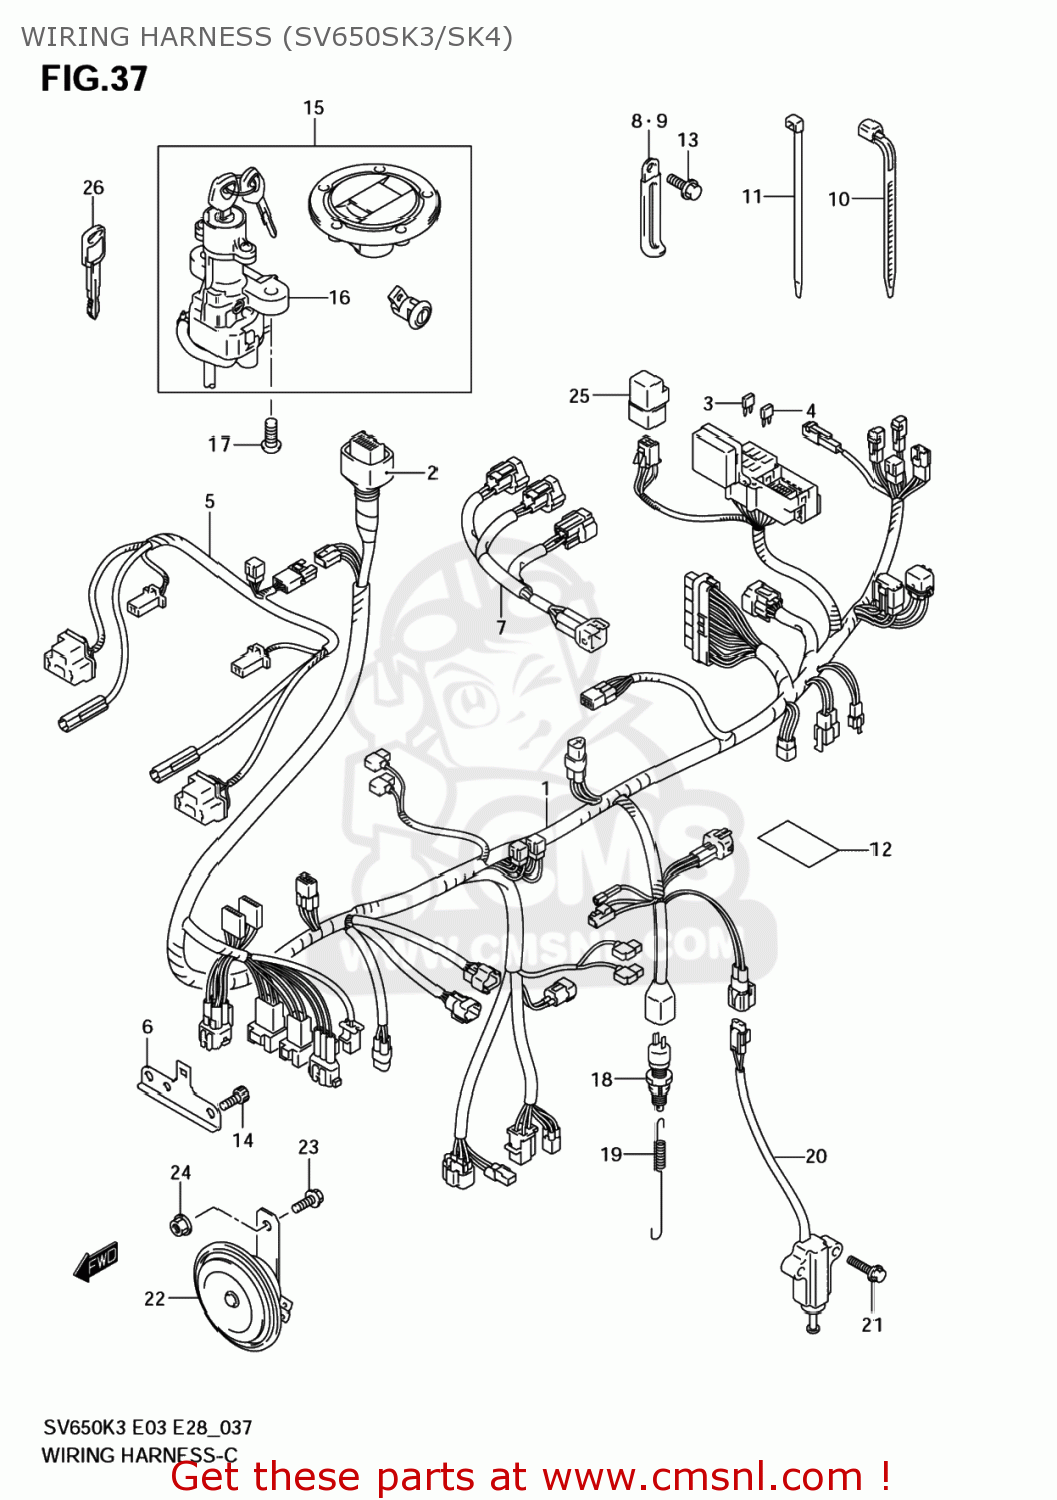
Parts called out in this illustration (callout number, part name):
1	HARNESS,WIRING NO.1
2	COVER,SPEEDOMETER COUPLER
3	FUSE(10A)
4	FUSE(15A)
5	HARNESS,WIRING NO.2
6	HOLDER,COUPLER
7	WIRE,INJECTOR LEAD
8	CLAMP(L:45)
9	CLAMP(L:80)
10	CLAMP(L:125)
11	CLAMP(L:145)
12	TAPE,WIRING HARNESS(28X50X0.13
13	BOLT
14	BOLT,VAC.PIPE
15	LOCK SET
16	LOCK ASSY,STEERING
17	BOLT(8X20)
18	SWITCH ASSY,STOP LAMP
19	SPRING
20	SWITCH ASSY,SIDE STAND
21	BOLT
22	HORN ASSY
23	BOLT
24	NUT
25	RELAY ASSY
26	KEY,BLANK
